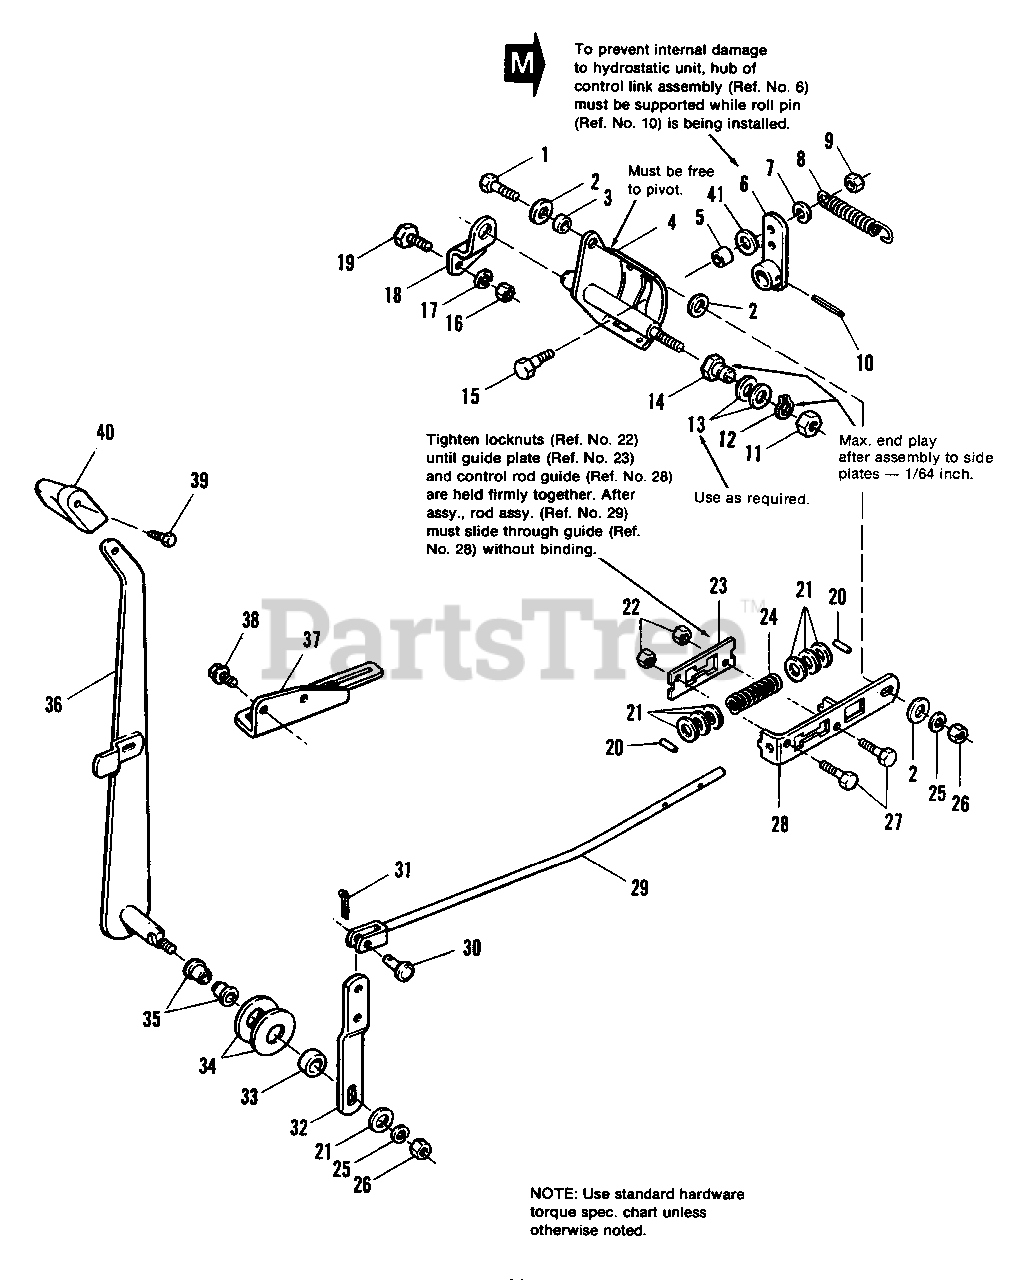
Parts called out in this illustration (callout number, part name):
1	CAPSCREW, Hex Hd., 3/8-16 x 1
2	WASHER, Plain, 5/16
4	SHAFT ASSY.
5	ROLLER, Cam
6	LINK ASSY., Control
7	LOCKWASHER, 1/4
9	NUT, Hex, Full, 1/4-20
10	PlN, Roll, 1/4 x 1-1/4
11	LOCKNUT, Hex, Jam, 1/2-13
12	RING, Retaining
13	SHIM (as required)
14	NUT, Adjusting
15	BOLT, Shoulder
16	NUT, Hex, Full, 5/16-18
17	LOCKWASHER, 5/16
18	BRACKET, Pivot
19	SCREW, Special
20	PIN, roll, 1/8 x 5/8
21	WASHER, Plain, 3/8
22	LOCKNUT, Hex, 1/4-20
23	PLATE, Guide
25	LOCKWASHER, 3/8
26	NUT, Hex, Full, 3/8-16
27	CAPSCREW, Hex Hd., 1/4-20 x 1-1/4
28	GUIDE, Control Rod
29	ROD ASSY., Control
31	PIN, Cotter, 3/32 x 3/4
36	LEVER ASSY., Control
37	QUADRANT
38	SCREW, Hex, Flange, Whiz, 5/16-18 x 1/2
39	SCREW, Self Tapping, 1/4-20 x 1-1/4
41	WASHER, Plain, 1/4
